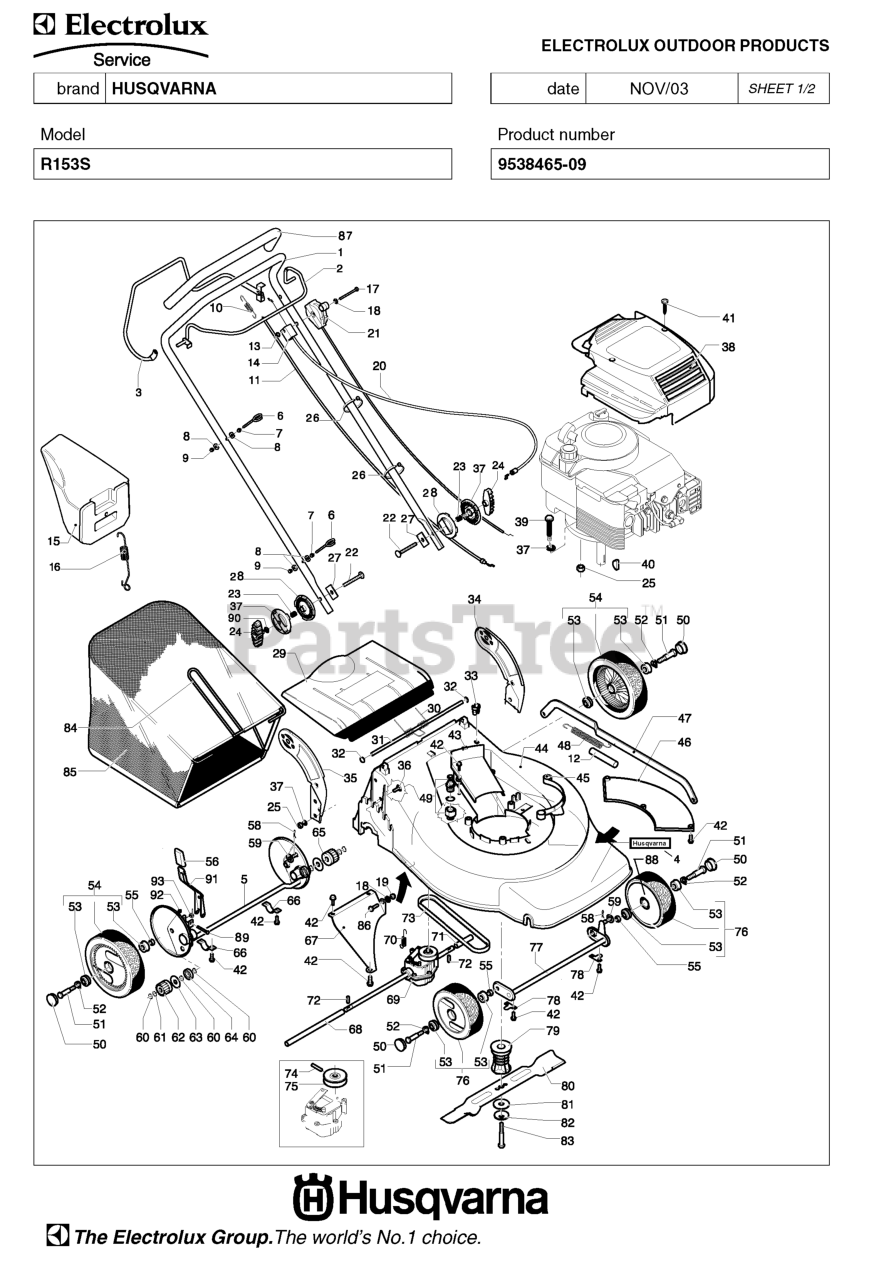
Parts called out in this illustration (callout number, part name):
42	Screws
58	Pins
60	Washers
